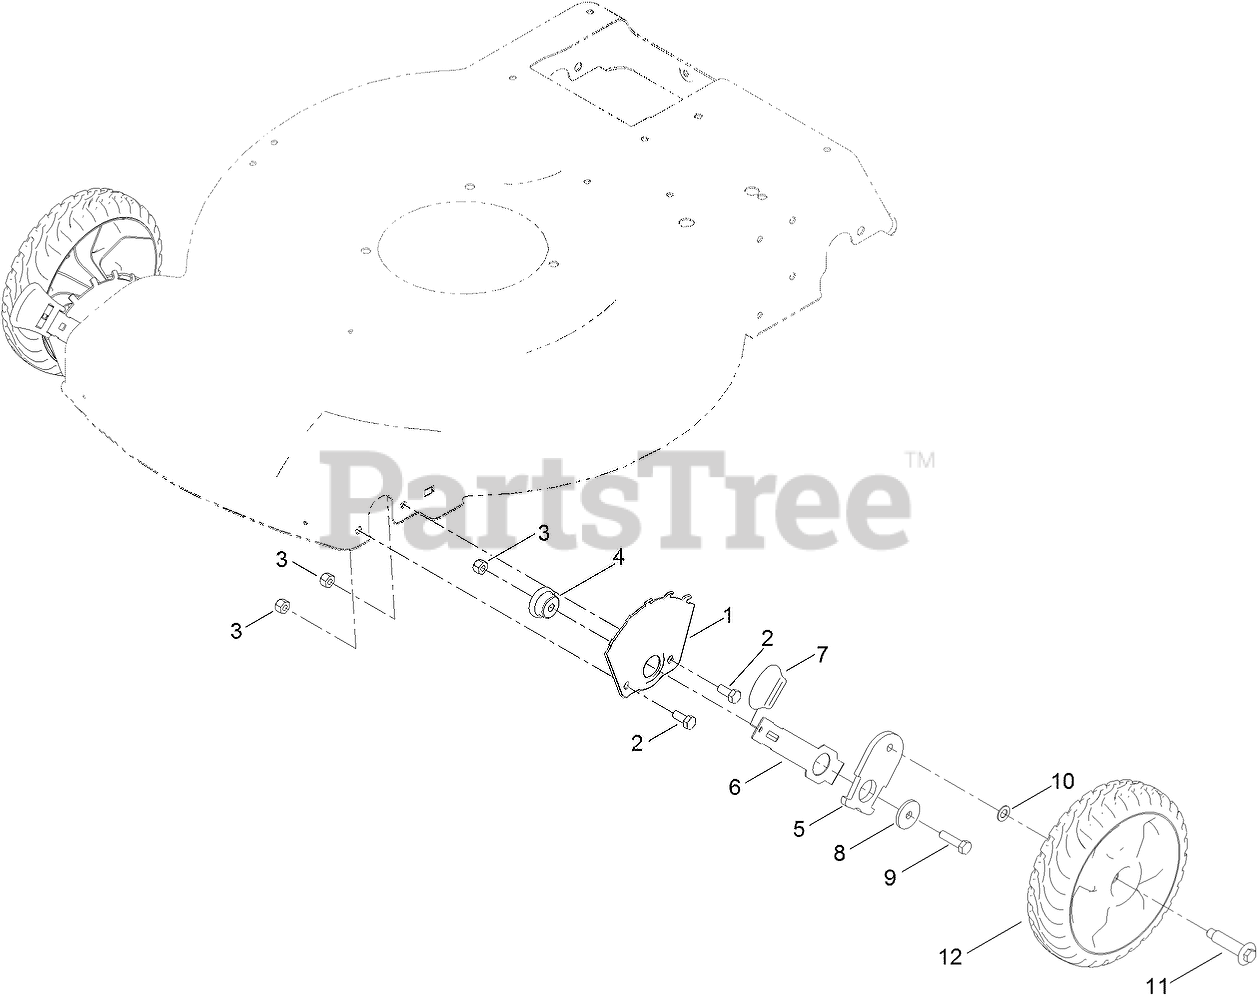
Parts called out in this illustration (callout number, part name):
1	PLATE-HOC, FRONT
2	SCREW-HH
3	NUT-HEX
4	BUSHING-MOUNT, HOC
5	ARM-PIVOT, FRONT
6	ARM-SPRING
7	KNOB-HOC
8	WASHER-FLAT
9	SCREW-HH
10	WASHER
11	BOLT-SHOULDER
12	81IN WHEEL ASM
